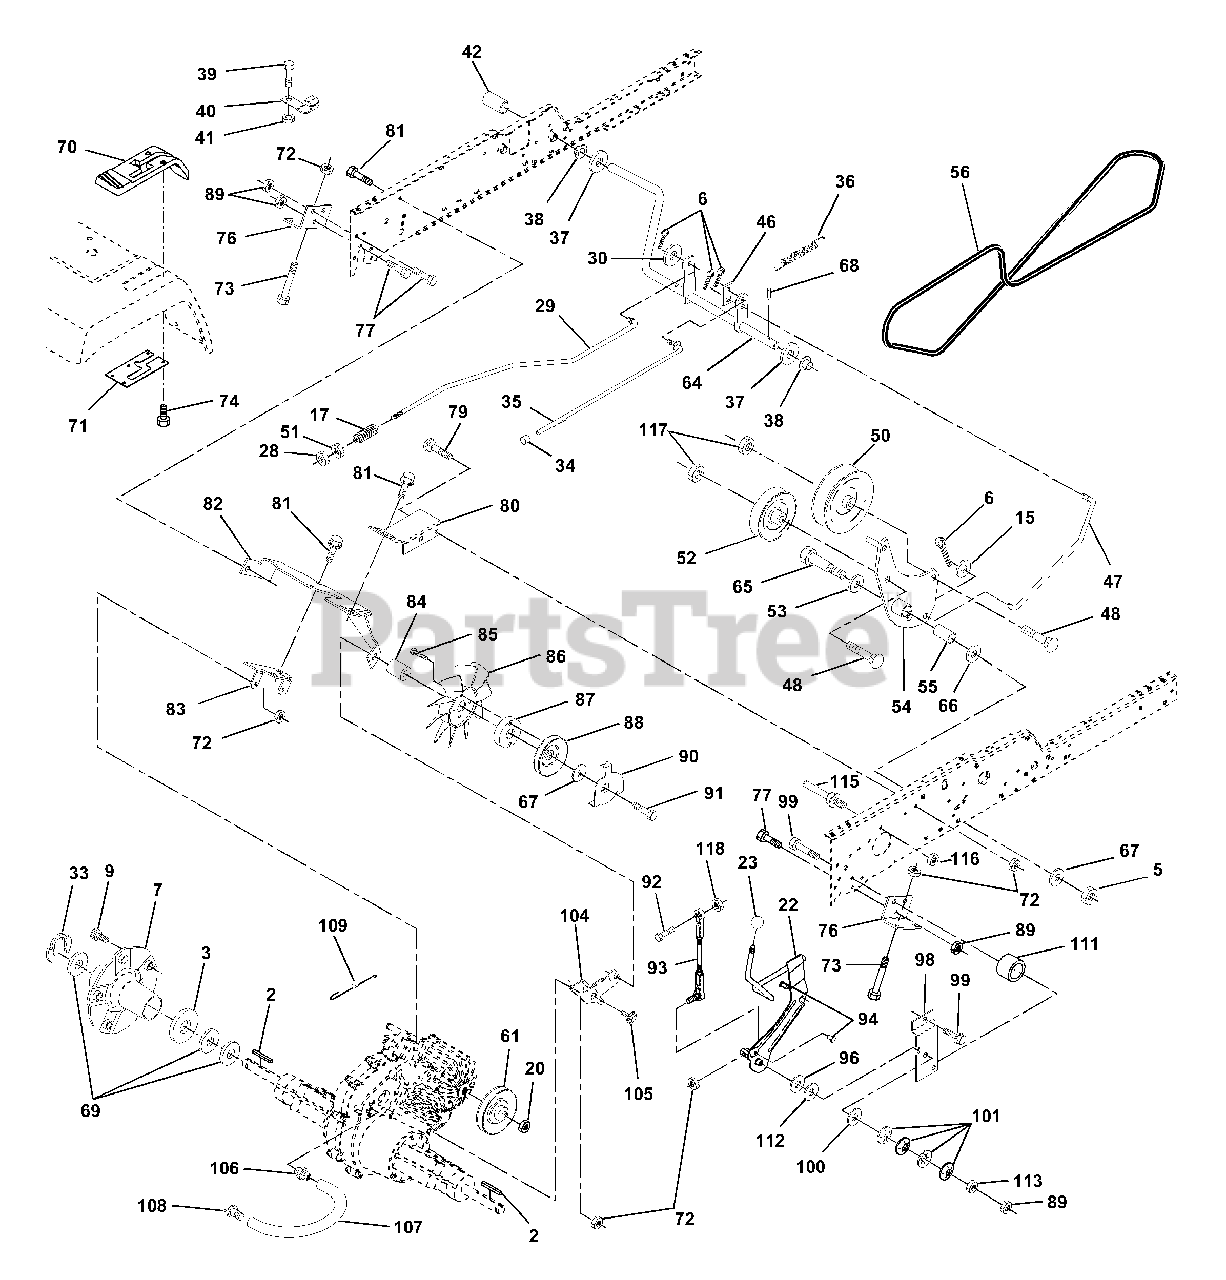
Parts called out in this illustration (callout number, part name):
2	Key 1/4 x 2.5
3	Washer Thrust Axle Harden
5	Nut Crownlock 3/8-16
6	Pin Cotter 1/8 x 3/4
7	Wheel Hub Asm.
9	Bolt Hub
15	Washer 13/32 x 13/16 x 16 Ga.
17	Spring Rod Brake
20	Nut Hex Jam Toplock 1/2-20
22	Shaft Arm Asm
28	Nut, Hex Jam 3/8-16
29	Brake Rod
30	Washer 13/32 x 1 x 16Ga
34	Cap Plunger
35	Rod Parking Brake
36	Spring Drive Ground
37	Washer 25/32 x 1-1/4 x 16 Ga.
39	Screw Fin #10-24 x 1
40	Actuator Interlock Switch
41	Nut Toplock #10-24 Unc
42	Cover Pedal
46	Retainer Spring
47	Clutch Rod
48	Bolt Carriage 3/8-16 x 1-1/2 Gr. 5
50	Pulley Idler Flat
51	Nut Lock Hex 3/8-16
52	Pulley Idler Grooved
53	Washer Hardened
54	Clutch Arm Asm
55	Bearing, Idler
61	Pulley Transaxle
64	Shaft Asm Brake Parking Clutch
65	Bolt Shoulder
66	Washer Hardened
67	Washer 13/32 x 13/16 x 12 Ga
70	Console Hydro Fender
71	Plate Console Shift
72	Nut Crownlock 5/16-18
73	Bolt Hex Flghd 5/16-18 x 3 Gr. 5
74	Screw, Hex Wsh Hi-Lo 1/4-1/2
76	Bracket Transaxle
77	Bolt Fin Hex 7/16-14 x 1
79	Bolt Carriage 5/16-18 x 5/8
80	Bracket Torque RH
81	Screw 3/8-16 x 3/4
82	Bracket Mount Torque/Fan
83	Strap Torque Mid
85	Screw #10-24 x 1-1/4
86	Fan 7" Hydro
87	Adapter Fan
88	Pulley Idler
89	Nut, Crownlock 7/16-14
90	Keeper Belt
91	Screw Thdrol 3/8-16 x 2-3/4
92	Bolt Fin Hex 5/16-18 x 1.75
93	Link Shift Asm
94	Fastener Christmas Tree
96	Washer Nickel Plated
98	Bracket Shift
99	Screw 3/8-16 x 1-1/2
100	Washer Compression
101	Washer Bellville
104	Bracket Idler
105	Screw Tap 1/4-20 x 1/2
106	O-Ring Asm. Hydro Gear
107	Line Fuel Hydro
108	Cap Vent
109	Spring Return Brake
111	Spacer Shift Lever VGTH
112	Washer Nylon High Temp
113	Nut Hex ASF 7/16-14 UNC
115	Keeper Belt Gnd Dr.
116	Nut Lock Hex Flange 5/16-18
117	Nut Lock Flg. 3/8-16 UNC
118	Nut Lock Hex w/Ins 5/16-18 Unc
